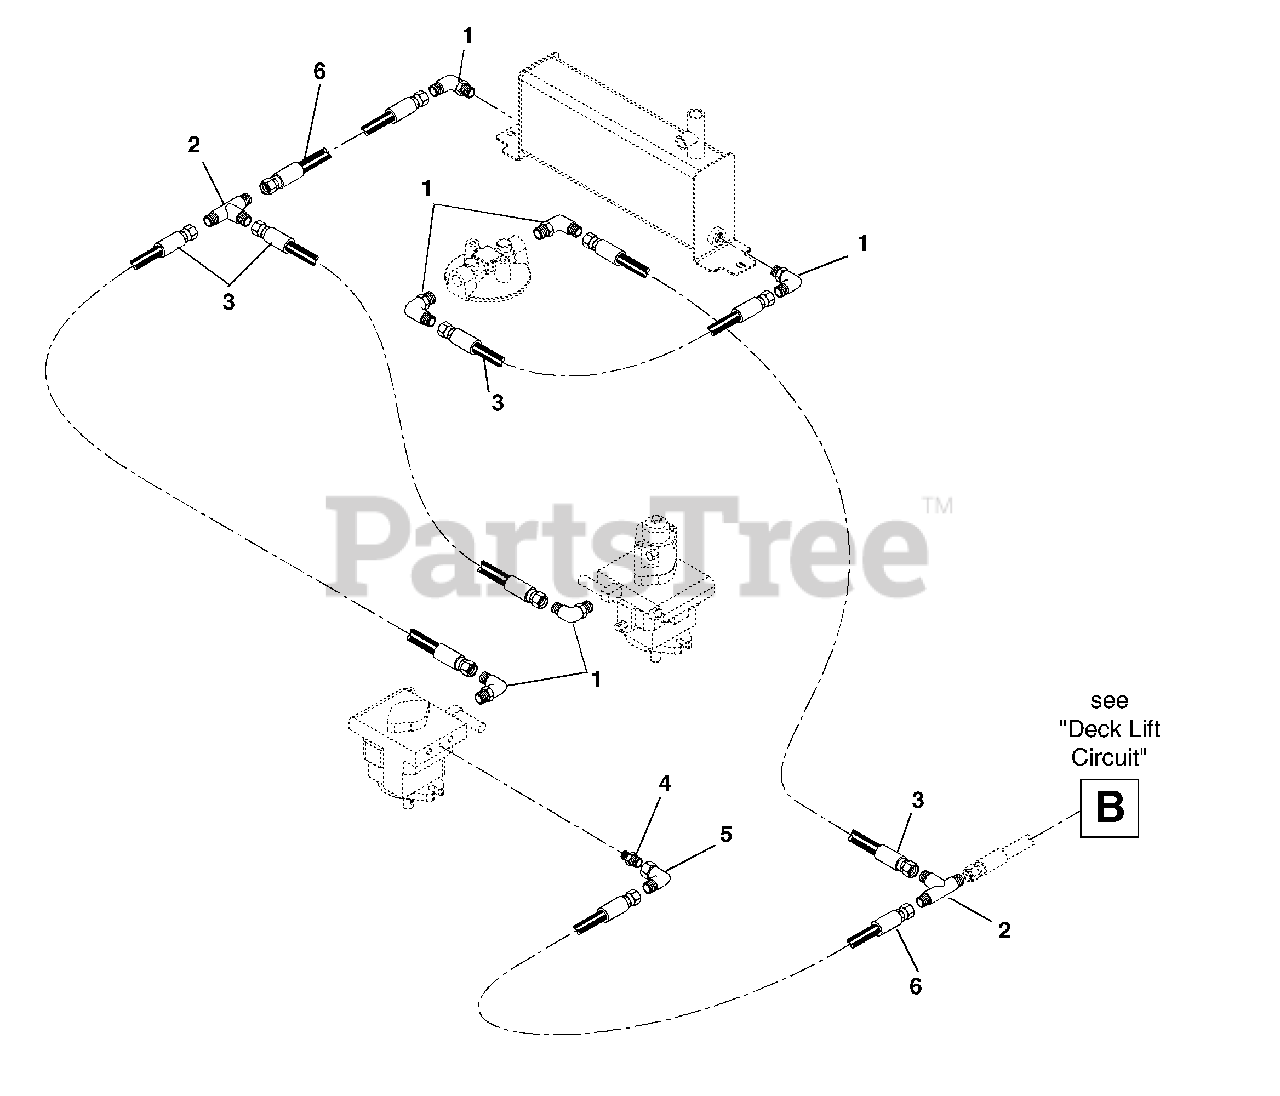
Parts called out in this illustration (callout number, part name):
1	Adapter
2	Adapter-Tee .56-18
3	Hose-Hydraulic Valve to Tank
5	Adapter
6	Hose-Pump to Tee
